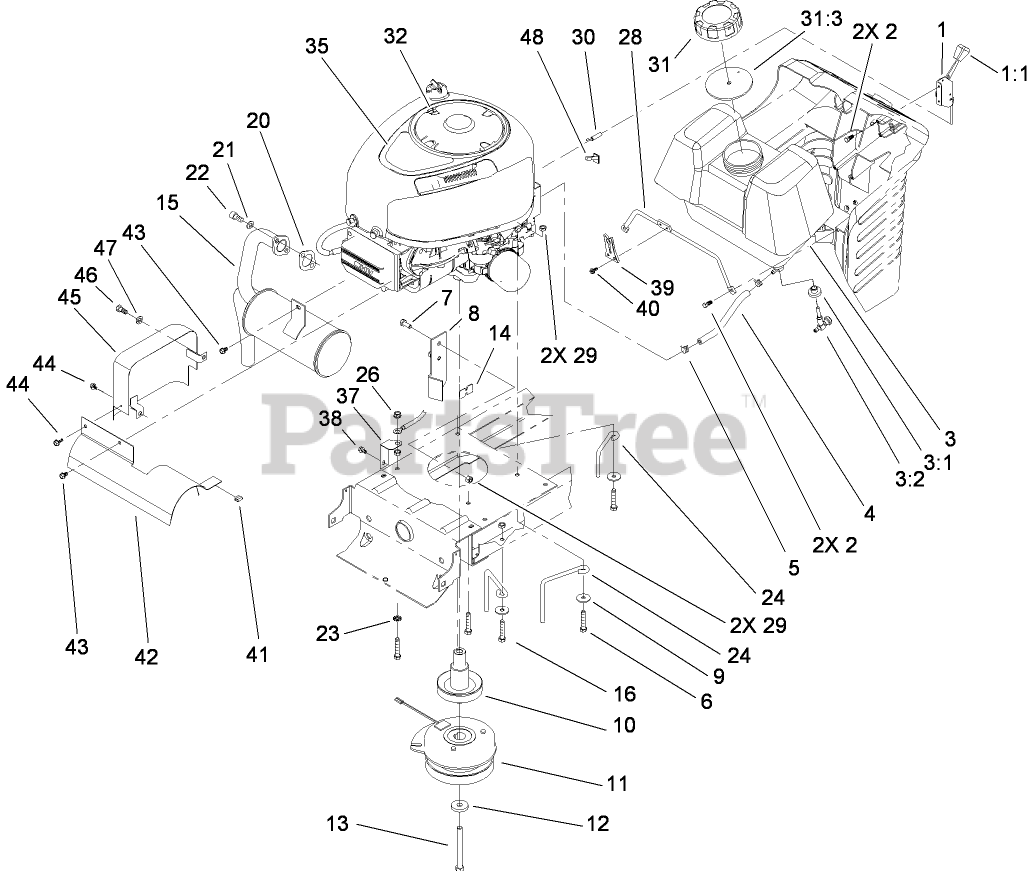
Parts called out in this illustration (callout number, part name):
1	THROTTLE CONTROL ASM
2	SCREW-SPECIAL
3	GAS TANK ASM
3:1	BUSHING
3:2	VALVE-FUEL
4	HOSE-FUEL
5	CLAMP-HOSE
6	SCREW-HH
7	SCREW-HH
8	STOP-CLUTCH
9	WASHER-PIVOT
10	PULLEY-ENGINE
11	CLUTCH-PTO, ELECTRIC
12	WASHER
13	SCREW-HH
14	BUMPER
15	MUFFLER-EXHAUST
16	SCREW-HWH, TAPTITE
20	GASKET-EXHAUST
21	WASHER-LOCK
22	SCREW-HSH
23	WASHER-LOCK
24	GUIDE-BELT, RH
26	NUT-KEPS
28	ROD-TANK, GAS
29	NUT-LOCK, NI
30	THROTTLE CABLE ASM
31	GAS CAP ASM
31:3	GASKET-CAP, GAS
32	Loose Parts Package
35	DECAL-ENGINE
37	BRACKET-GROUND
38	SCREW-HWH
39	LATCH-HOOD
40	SCREW-HWH
41	CLIP-TINNERMAN
42	EXHAUST SHIELD ASM
43	SCREW-HWH
44	SCREW-HWHTF
45	HEAT SHIELD ASM
46	SCREW-HH
47	WASHER-LOCK
48	REDUCER-THROTTLE, RPM
